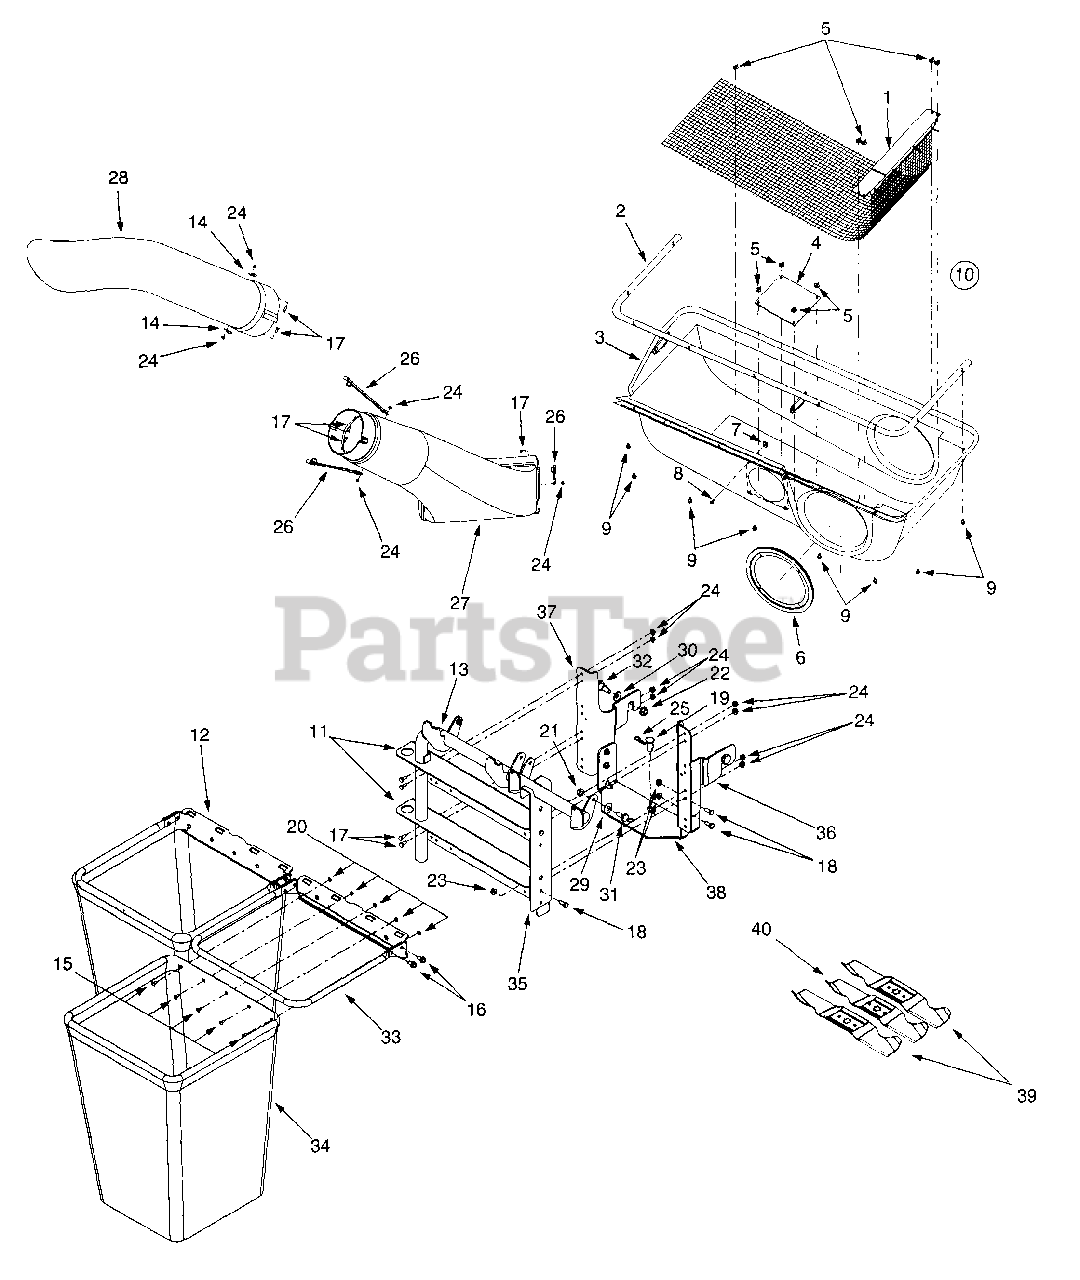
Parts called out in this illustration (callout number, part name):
3	Grass Catcher Cover
4	Plastic Plate, 1/8 x 5.6 sq.
5	Zip Twist Fastener
6	Tube Seal
7	U-Type Speed Nut, #10-24
8	Screw, #10-16 x .5
9	Hex Screw, 1/4-20 x .5
10	Cover Assembly
14	Retainer Hook Bracket
15	Screw, #10-24 x .5
16	Self Tapping Screw, 5/16-18 x .625
17	Hex Cap Screw, 1/4-20 x .62
18	Hex Cap Screw, 5/16-18 x .75
19	Clevis Pin
20	Hex Sems Nut, 10-24
21	Hex Flange Lock Nut, 3/8-16
22	Hex Flange Lock Nut, 7/16-20
23	Hex Flange Lock Nut, 5/16-18
24	Hex Flange Lock Nut, 1/4-20
25	Internal Cotter Pin, .148 x 3
26	Retainer Strap Assembly
27	Discharge Chute
28	Chute Tube
29	Bell Washer
30	Bell Washer, .45 x 1.0 x .062
31	Shoulder Screw, .50 x .27, 3/8-16
32	Shoulder Screw, .625 x .5, 7/16-20
34	Bag
39	Star Center Blade, 16.28
40	Star Center Blade, 14.88
